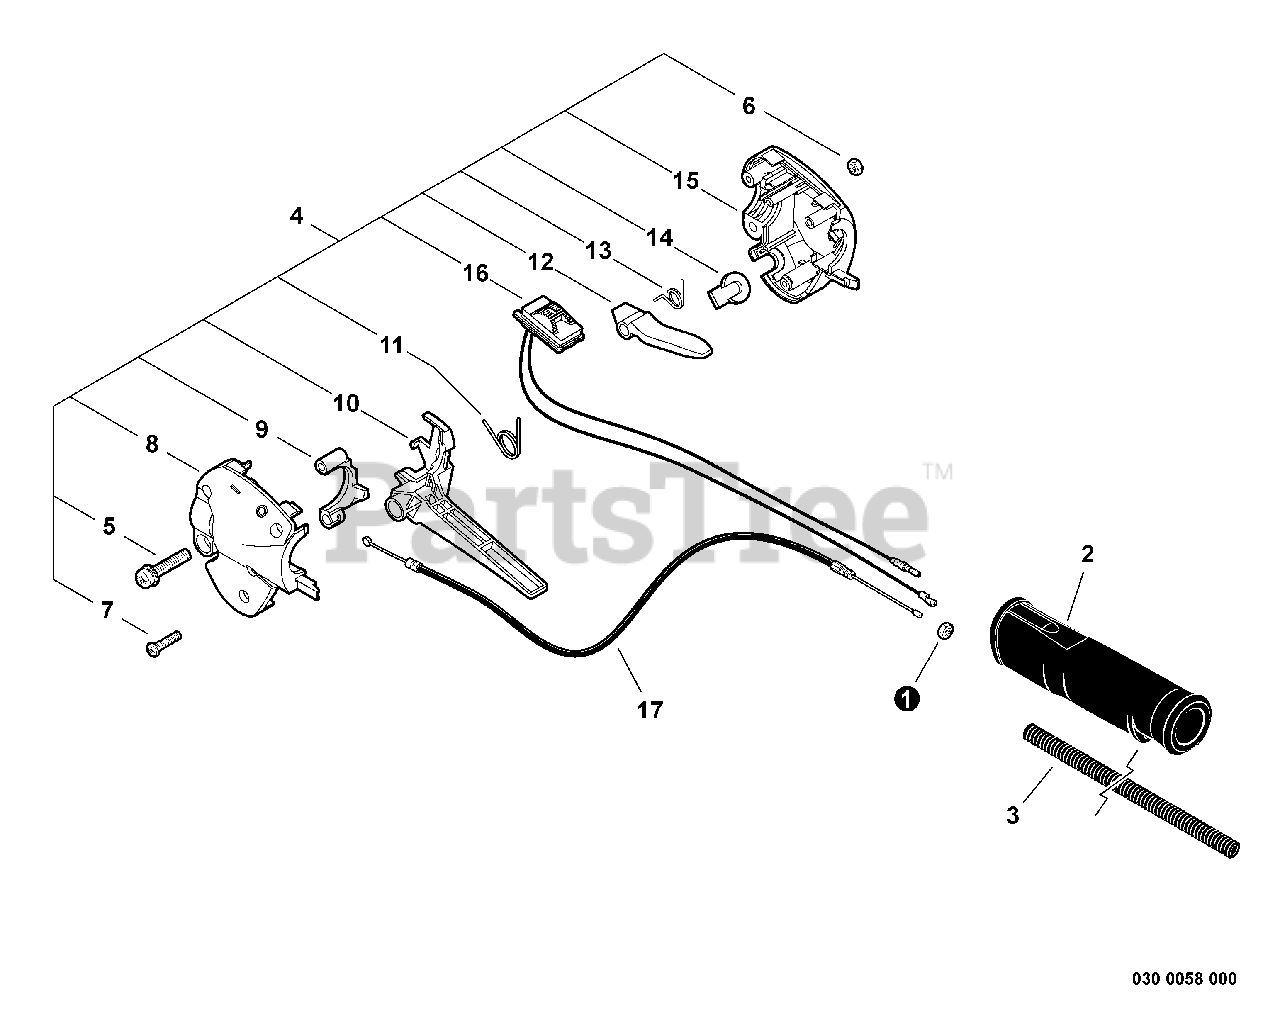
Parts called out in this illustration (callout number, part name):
2	GRIP, HANDLE
3	TUBE, PROTECTIVE - CORRUGATED
4	CONTROL HANDLE ASSY
5	SCREW - 5X20
6	NUT - 5
7	SCREW - 4X20 -- TAPPING
8	HANDLE, CONTROL - LEFT
9	LOCKOUT, THROTTLE
10	TRIGGER, THROTTLE
11	SPRING, TRIGGER
12	LEVER, TRIGGER LOCKOUT
13	SPRING, LOCKOUT LEVER
15	HANDLE, CONTROL - RIGHT
16	IGNITION SWITCH ASSY
17	CABLE, THROTTLE
